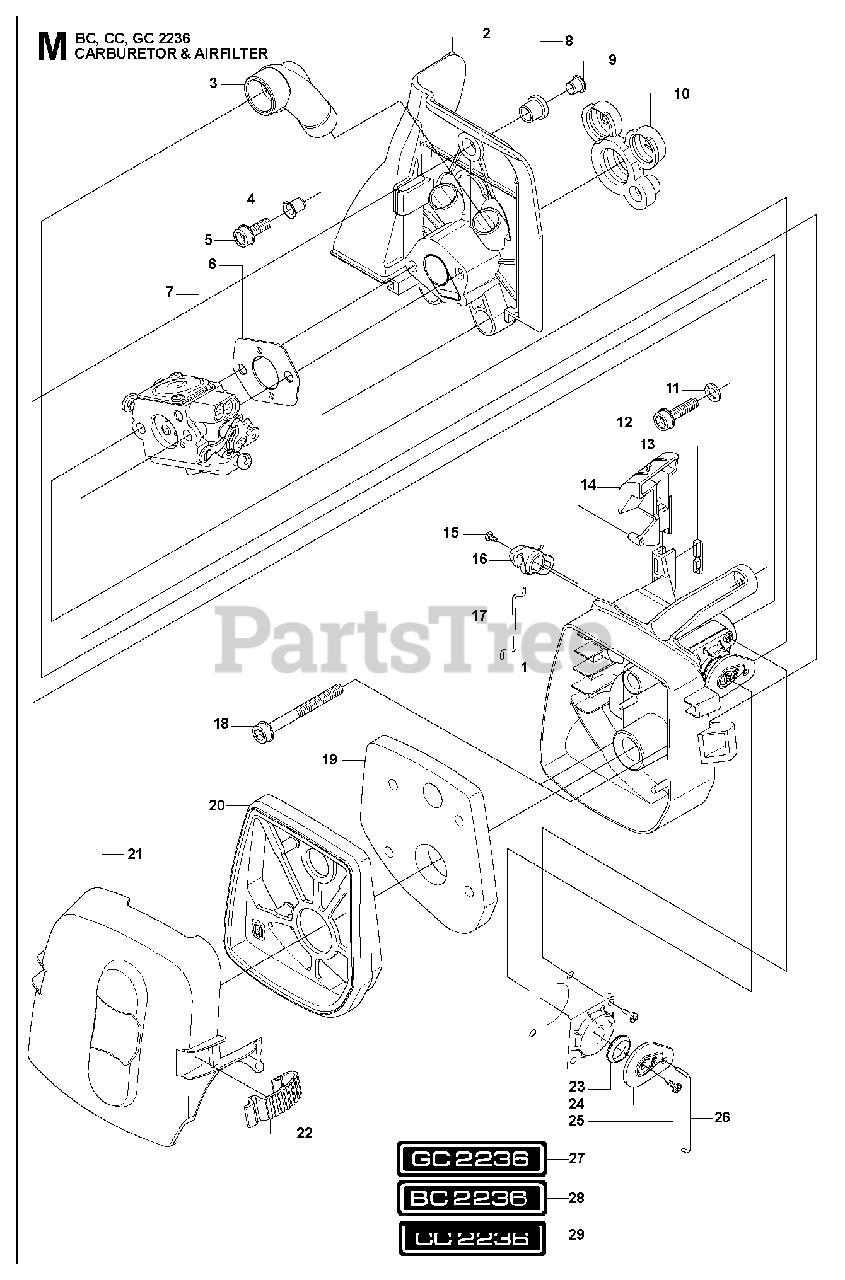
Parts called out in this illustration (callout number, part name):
1	FILTER HOLDER
2	PARTITION
4	SLEEVE
7	CARBURETOR C1QEL36
8	SLEEVE
9	SLEEVE
13	RAIL
14	CHOKE CONTROL
15	SCREW
16	LEVER
17	THROTTLE ROD
19	AIR FILTER
21	COVER AIR FILTER
23	BELLOWS
24	LEVER
25	SCREW
26	THROTTLE ROD
29	LABEL
